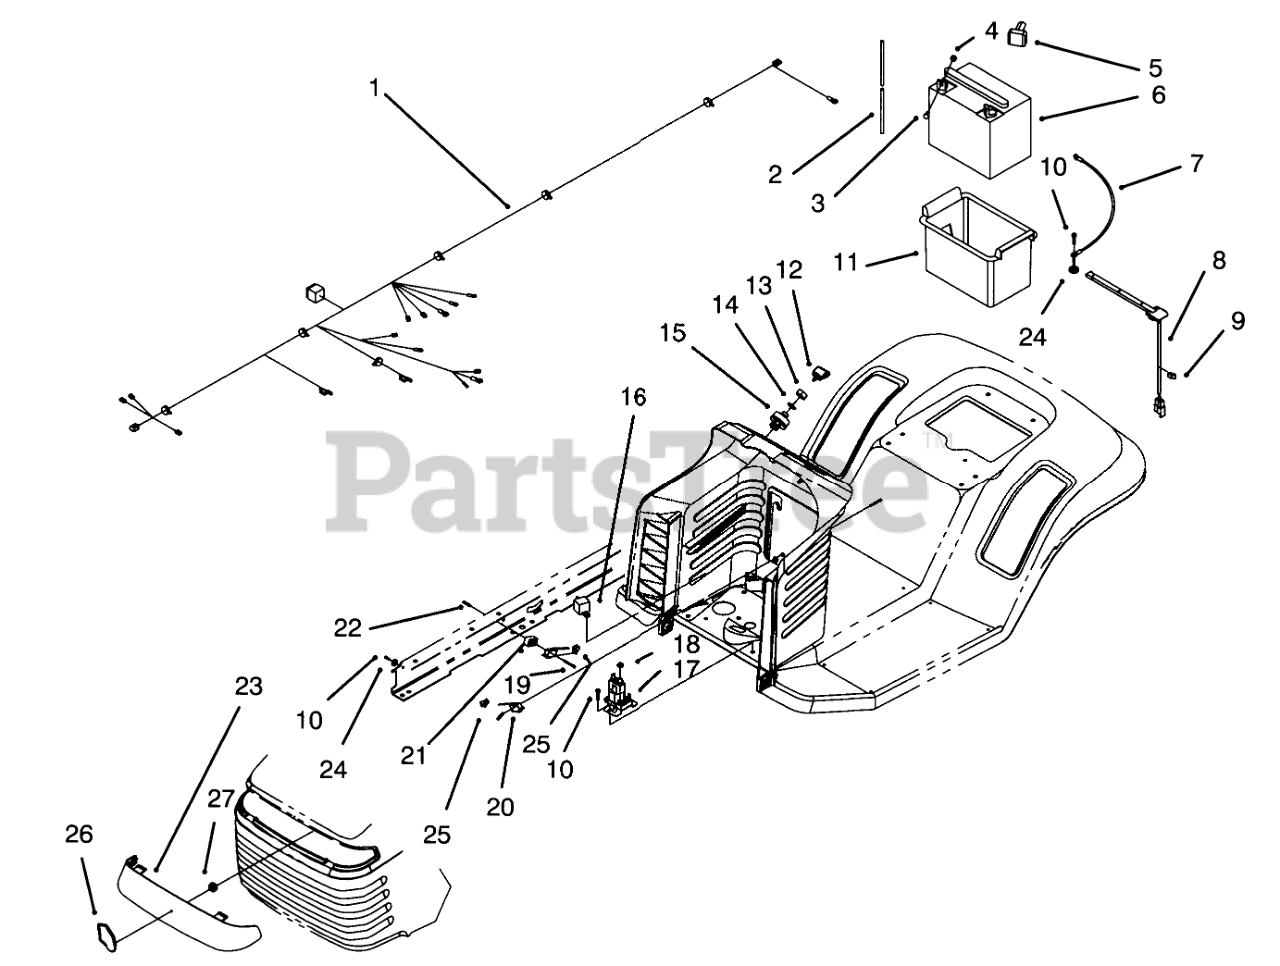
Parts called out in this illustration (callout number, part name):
1	Harness-Wire
2	TUBE-BATT DRAIN/80-2600
3	SCREW-HH
4	NUT-WING
5	BOOT-TERMINAL
6	Battery
7	WIRE ASM
8	SWITCH-SEAT
9	CLIP-RETAINER, WIRE
10	SCREW-HWH
11	BOX-BATTERY
12	KEY-IGNITION
13	NUT-HH
14	WASHER-TOOTH, INTERNAL
15	Key Switch ASM
16	RELAY
17	Solenoid
18	NUT-KEPS
19	Screw
20	SWITCH-MICRO
21	SPACER
22	NUT-SPEED
23	LENS-HEADLIGHT
24	WASHER-LOCK/EXT
25	PLUNGER-SEAL
26	EMBLEM-GRILLE WHEELHORSE
